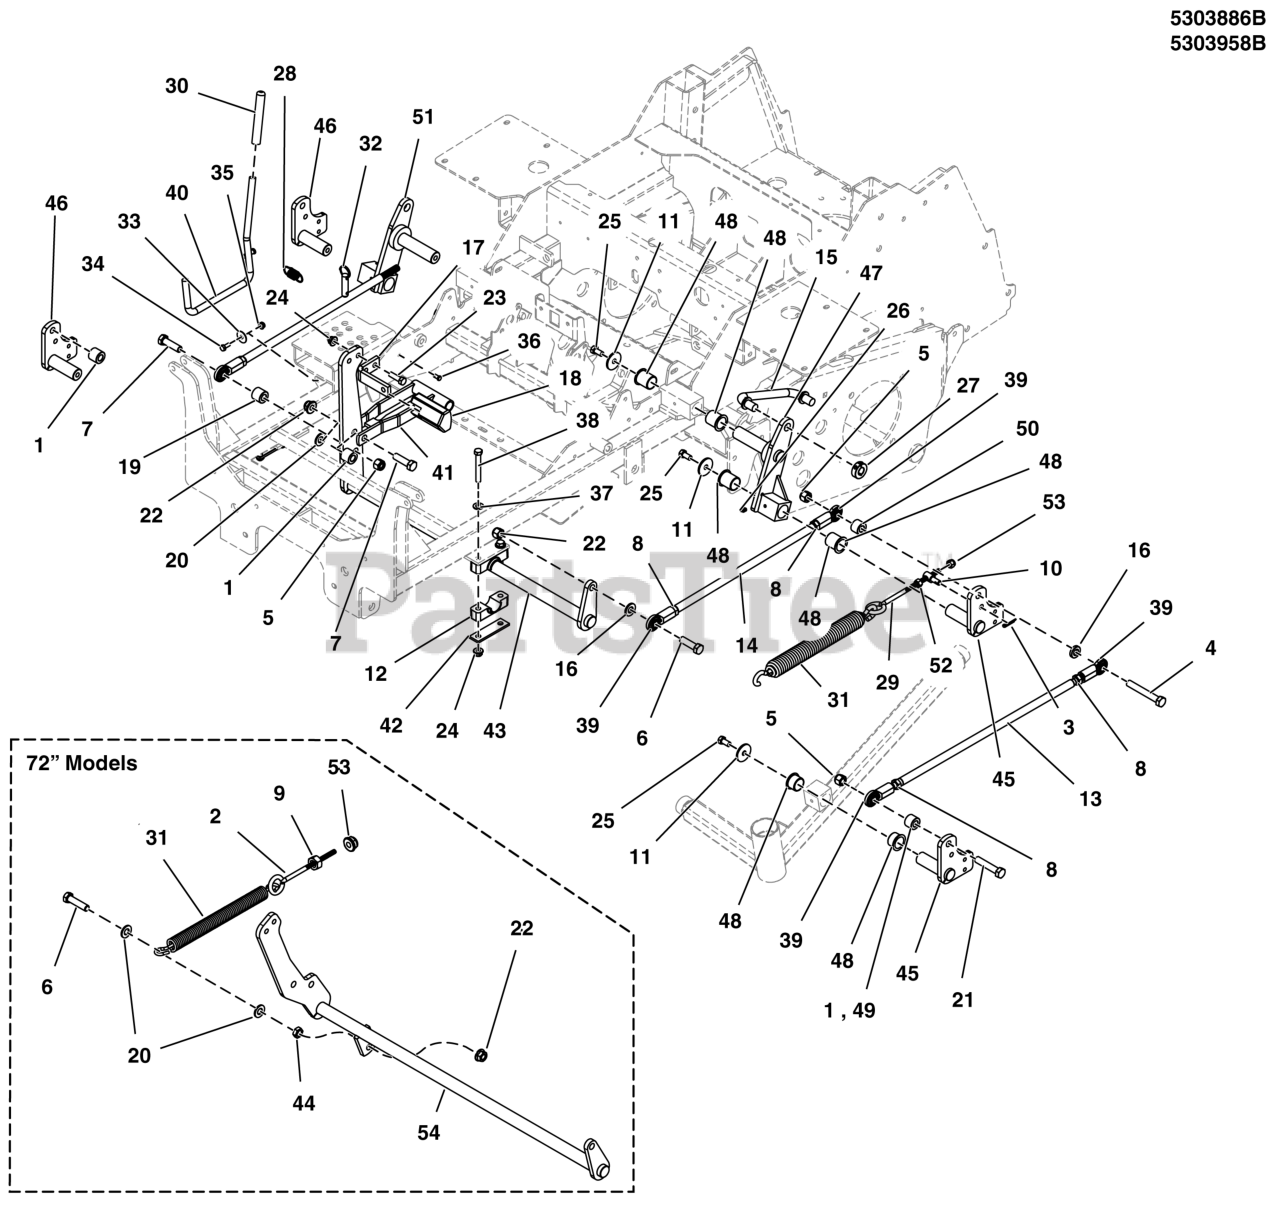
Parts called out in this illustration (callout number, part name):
1	SPACER, .52 X 1.00 X .75, CZ
2	EYE BOLT, 3/8-16 X 5, 2.88THRD, 1EYE, CZ
3	* PIN, COTTER, 1/8" X 3/4
4	BOLT, 1/2-13 X 3" GD5 CZ
5	NUT, 1/2-13 HEX NYLON LOCK
6	BOLT, 1/2-13 X 2" GD5 CZ
7	BOLT, 1/2-13 X 2-1/2" GD5 CZ
8	NUT, 1/2-20 Hex Jam
9	NUT, 3/8-16 Hex Large Serrated Flange
10	* ADJUSTER, DECK HANGER
11	WASHER, .390 X 1.50 X .109, YZ
12	PIVOT BLOCK, PLASTIC
13	ROD, DECK LIFT, EXTERNAL THRD, 20.63
14	BAR, DECK LIFT, 17.75"
15	ROD, SUSPENSION LINK, IS700, CZ
16	SPACER, .52 X 1.00 X .22, PM, CZ
17	PEDAL, FOOT - BLK
18	PEDAL, Rubber
19	SPACER, .52 X 1.00 X .88, PM, CZ
20	WASHER, 1/2 SAE
21	BOLT, 1/2-13 X 2-3/4 GD5 CZ
22	NUT, Hex Flange, Nylock, 1/2-13
23	BOLT, 3/8-16 X 1-1/4" GD5 CZ
24	NUT, 3/8 - 16 HEX NYLOCK FLANGE
25	BOLT, 3/8-16 X 3/4, PLT W/PATCH
26	GREASE FITTING, 1/4-28 Straight
27	COLLAR, 5/8" Split
28	SPRING-EXT, .740 ODX2.025LGX.072WR, BLK
29	EYE BOLT, 3/8-16 X 8, 3THRD, 1EYE, CZ
30	GRIP, FOAM, .475 X 4.35 X .095
31	SPRING-EXT, 1.393 ODX13.25LGX.218WR, BLK
32	PIN, HITCH, 1/2 X 2.00 OAL, YP
33	WASHER, 1/4" Fender
34	HHCS, 1/4-20 X 0.625, GR5, ZINC/CLEAR
35	NUT, 1/4-20 Hex Nylock Flange
36	PIN, CLEVIS, 1/4 X 1/2, PLATED
37	WASHER, 3/8 SAE
38	BOLT, 3/8-16 X 2-3/4" GD5 CZ
39	JOINT-BALL .500-20 THD .500ID, CLR ZINC
40	WELD, Rod, Deck Lift - BLK
42	PLATE, PIVOT BLOCK SUPPORT - BLK
43	WELD, DECK LIFT SHAFT - RED (61)
44	NUT, Hex, Jam, 1/2-13
45	WELD, DECK LIFT LEVER, LH - BLK
46	WELD, DECK LIFT LEVER, RH - BLK
47	WELD, REAR LIFT - LH - BLK
48	BUSHING, 1.00 X 1.13 X 1.38, Plastic
49	SPACER, .52 x 1.00 x 1.00
50	SPACER, .52 X 1.00 X .44, CZ
51	WELD, REAR LIFT - RH - BLK
52	NUT, 3/8-16 HEX, YZ
53	NUT, 3/8-16 HEX NYLON LOCK
54	WELD, DECK LIFT SHAFT, 72
54	WELD, DECK LIFT SHAFT, 72 - BLK
